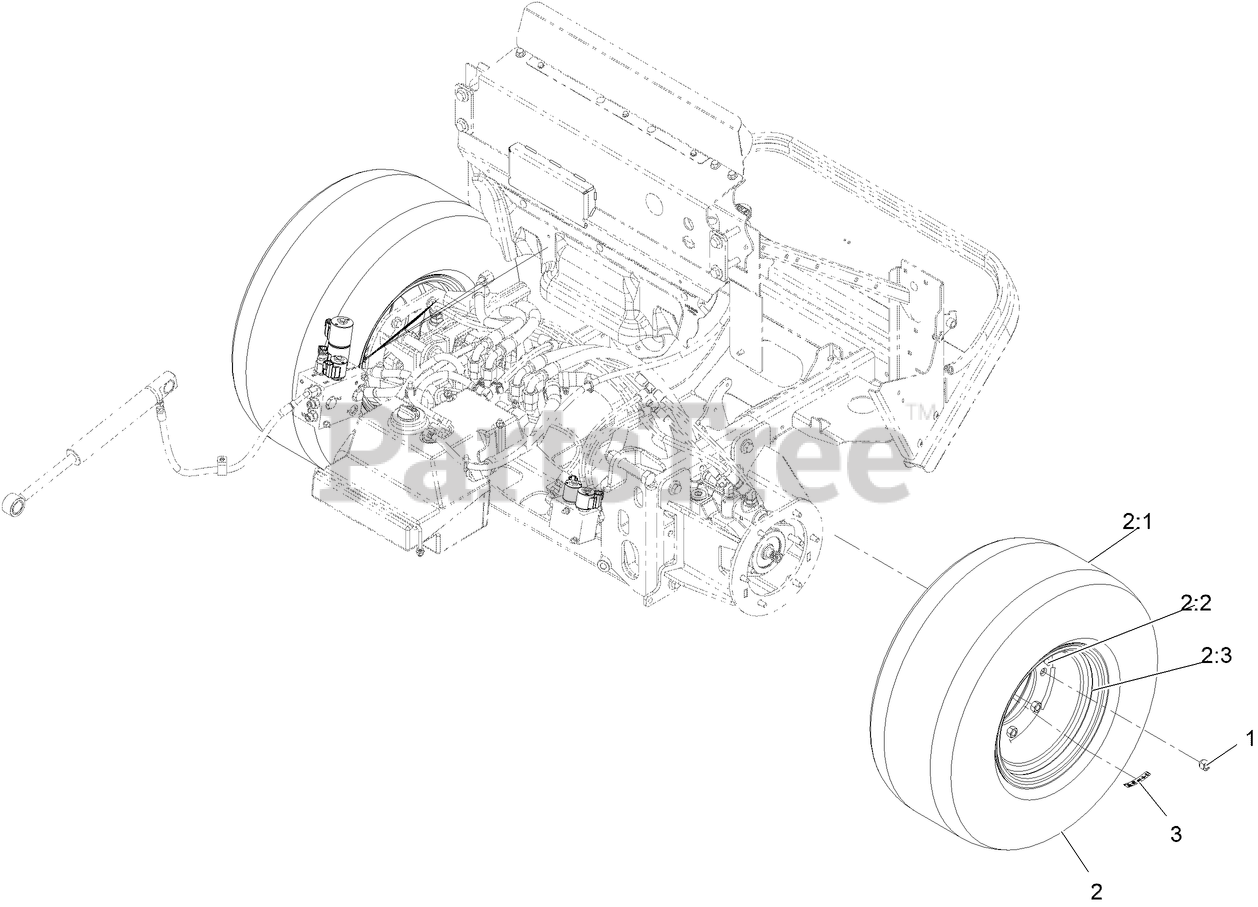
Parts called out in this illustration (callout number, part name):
1	NUT-LUG
2	ASM-TIRE 26X12-12, WHITE
2:2	Stem-Valve
2:3	WHEEL-12.0X8.5 8/8.0
3	DECAL-WHEEL HUB
